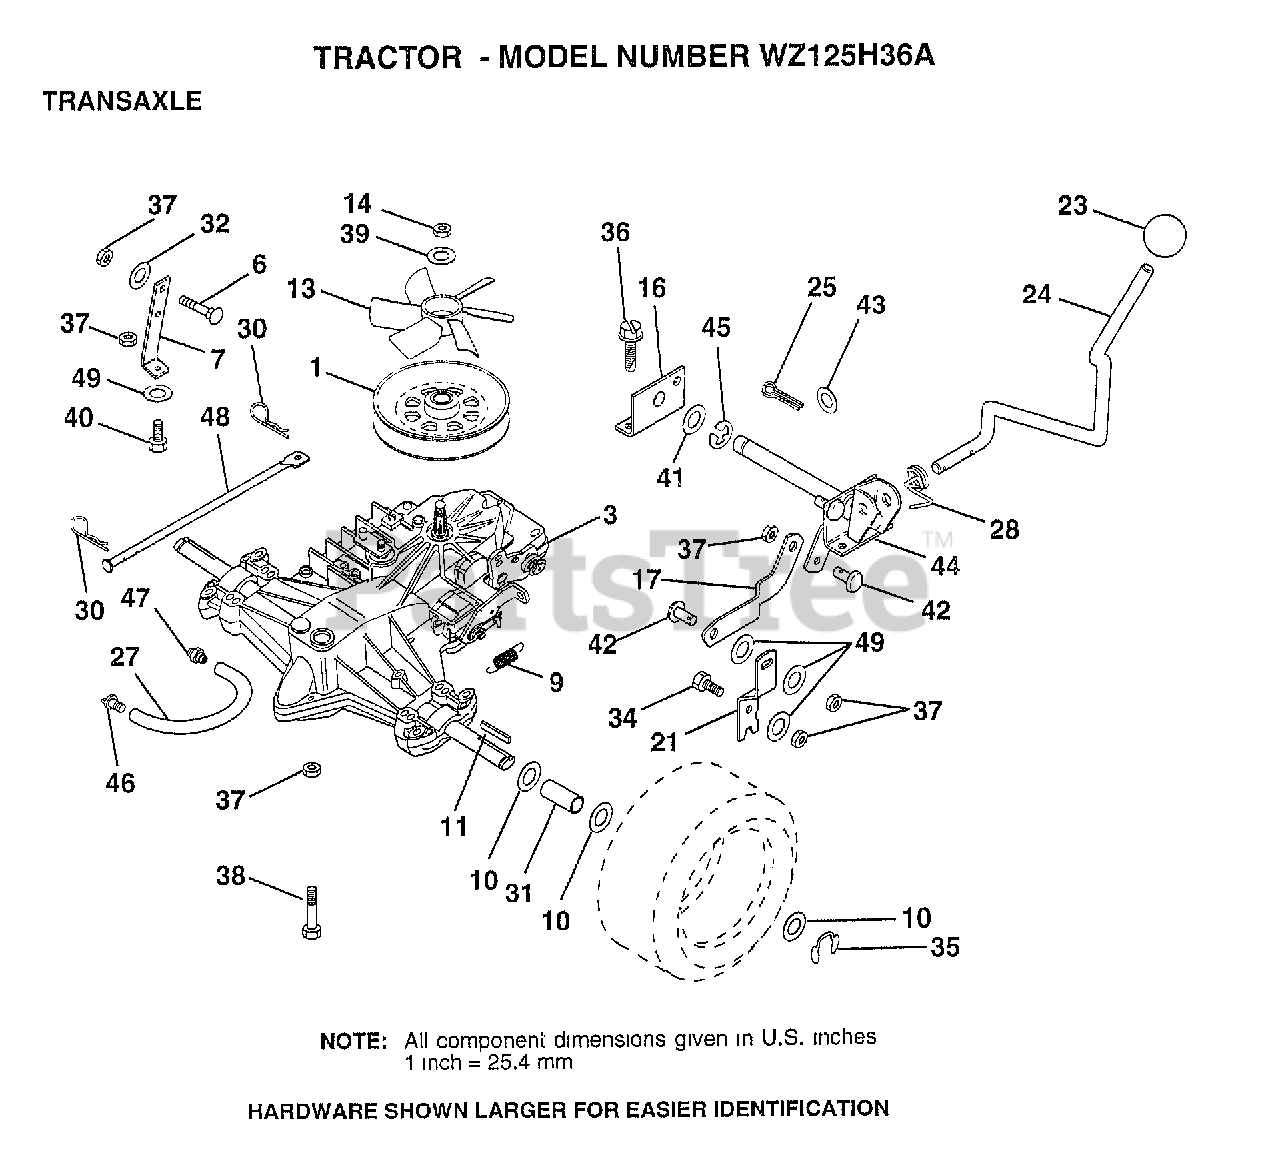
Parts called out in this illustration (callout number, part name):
1	PULLEY.V-GROOVE
3	BOLT
7	STRAP.TORQUE.HYD
9	SPRING.BRAKE.RETU
10	WASHER
11	SQUARE KEY
13	FAN.HYDRO.6FANS
14	"LOCKNUT,1/2-20UNF"
16	SUPPORT.HDLE.SHFT
17	LINK.SHIFT.HYD.LR
21	LEVER.SHIFT.TRANS
23	KNOB T (1/2-HOLE)
24	ROD.SHIFTER.HYD.
25	PIN COTTER 1/8
27	"LINE FUEL HYD 4"""
28	SPRING.TORSION.LR
30	RETAINER M
31	SPACER SPLIT
32	WASHER
35	E-RING LT
36	SCREW
37	NUT
38	BOLT.HX.FLG.5/16
39	WASHER
40	BOLT.HEX.5/16-1.5
41	WASHER
42	PIN.PIVOT.SHIFT.
43	WASHER
44	SHAFT.PIVOT.LR.
48	ACTUATOR.BYPASS
49	WASHER M
